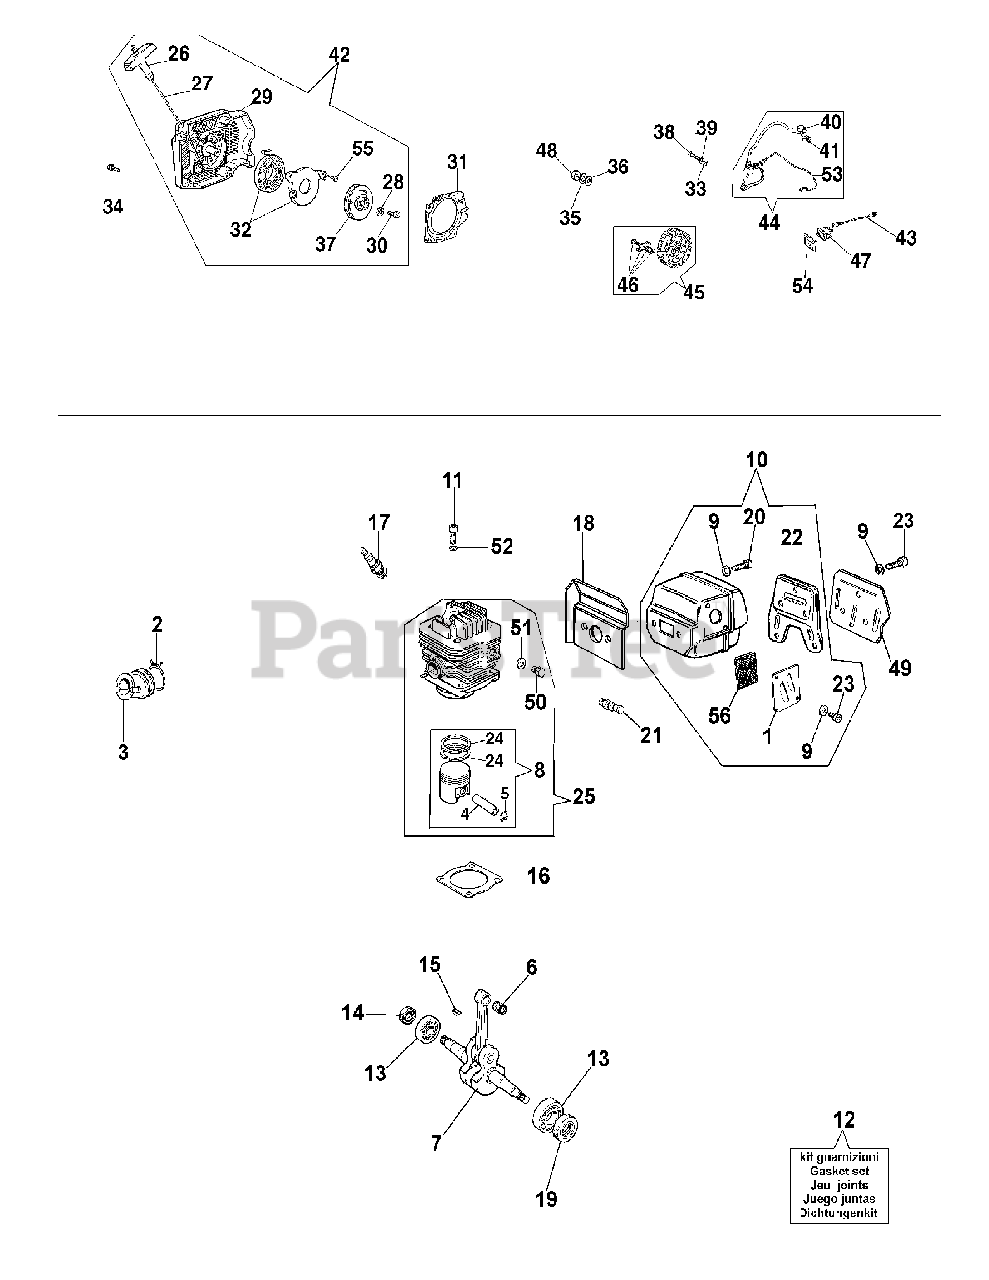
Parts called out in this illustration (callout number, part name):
8	COMPL. PISTON Ø46
10	MUFFLER COMPL.
14	SEALING RING
16	GASKET
17	SPARK PLUG
19	SEALING RING
21	DECOMPRESSOR
24	PISTON RING Ø46
25	COMPL.CYL. Ø46
29	STARTER CASE
32	SPRING and CASE
34	SCREW
42	STARTER ASSY
45	FLYWHEEL ASSY
47	SWITCH
49	MUFFLER GUARD
54	SWITCH GUARD
